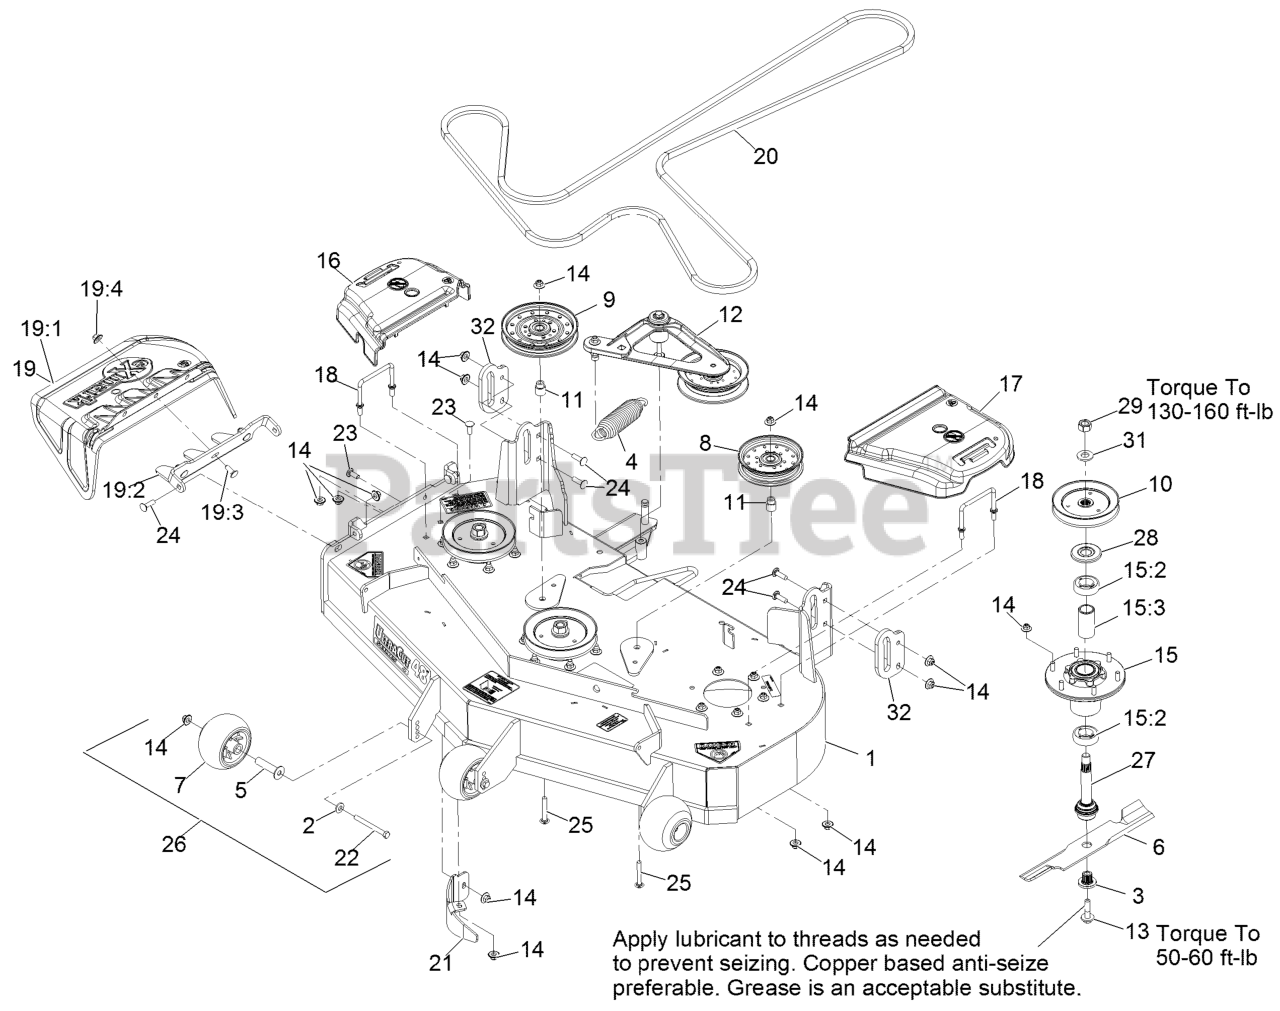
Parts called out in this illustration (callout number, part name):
1	ASM-484 DECK WITH DECALS
2	WASHER-BELLEVILLE
3	BUSHING,SPLINED
4	SPRING-EXTENSION
5	AXLE, ROLLER
7	ROLLER-SCALP, ANTI
10	SHEAVE,BLADE DRIVE 5.90
11	BUSHING-IDLER
12	DECK IDLER ASM
13	SCREW,SEMS 1/2-20 X 2.19
14	Nut-Nyloc 3/8-16 Flg
15	ASM-CUTTER HSG WITH BEARINGS
15:2	BEARING-BALL
15:3	SPACER-BEARING
16	COVER-BELT, RH
17	COVER-BELT, LH
18	WIREFORM-COVER
19	ASM,DISCHARGE CHUTE
19:1	CHUTE,DISCHARGE
19:2	BRACKET,DISCHARGE CHUTE
19:3	SCREW-CARR
19:4	Nut-Nyloc 3/8-16 Flg
20	BELT
21	BAFFLE-DOGLEG,LZE48
22	SCREW-HH 3/8-16 X 3 3/4 GR 8
23	SCREW-CARR
24	Bolt-Carriage 3/8-16 X 1 1/4
25	SCREW-CARR
26	KIT, ANTI-SCALP ROLLER
27	ASM-SPINDLE AND SEAL
28	GUARD,BEARING TOP .989
29	NUT-HEX
32	PLATE-REINF, PUSH TOWER
